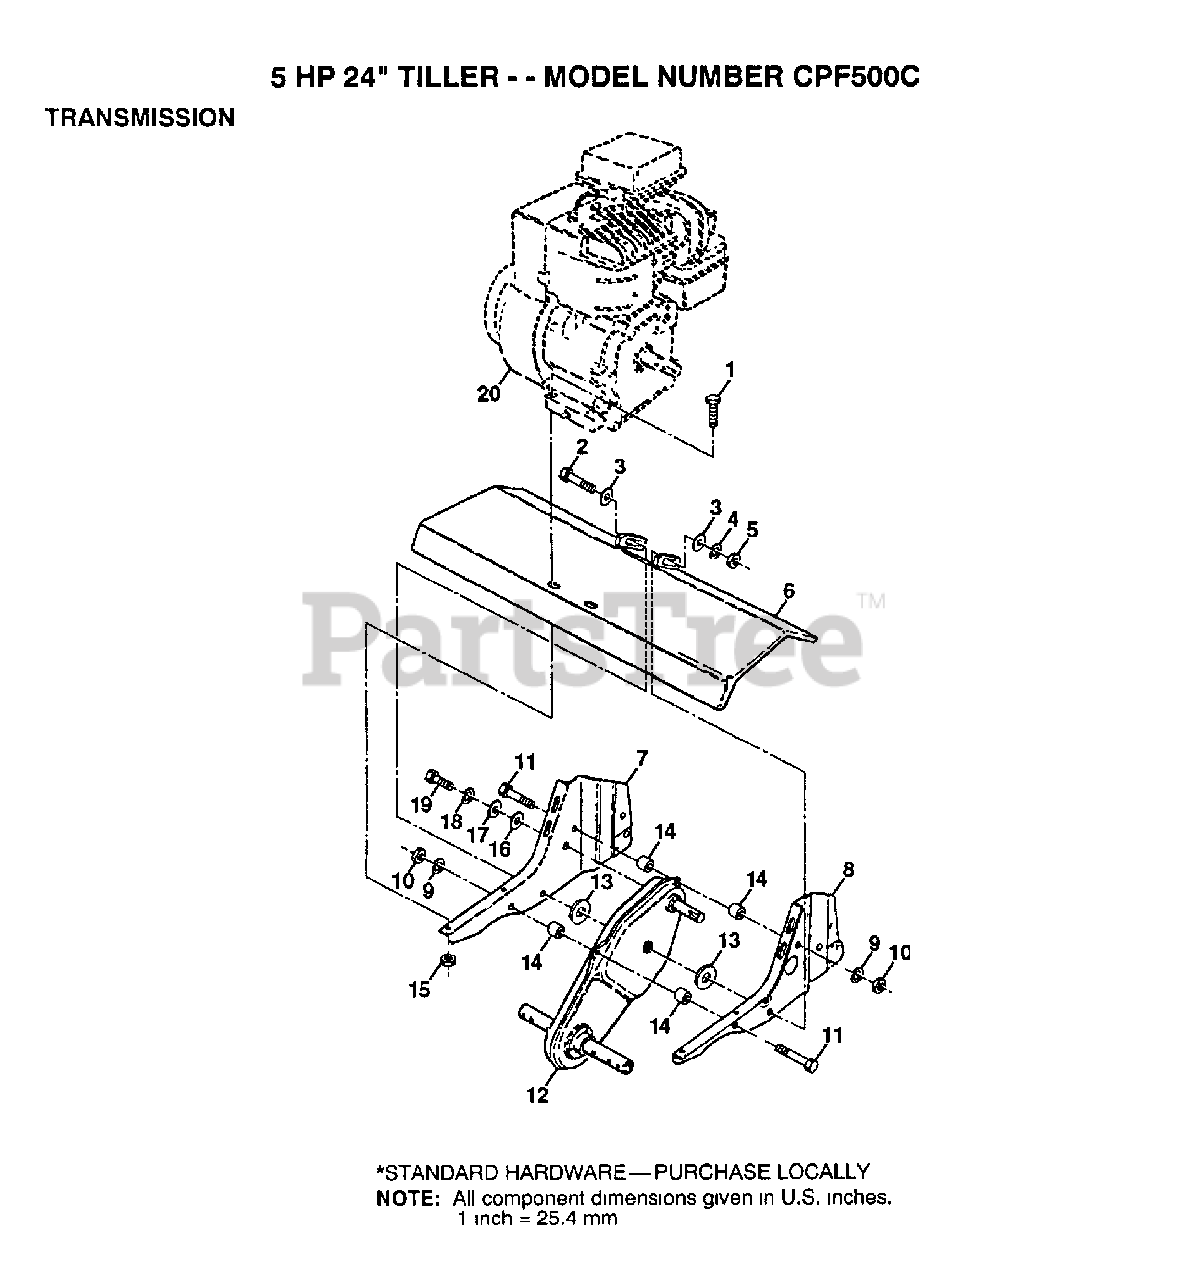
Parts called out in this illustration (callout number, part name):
1	BOLT.HEX.5/16-1.5
2	BOLT.3/8-24X3.75
3	WASHER
4	LOCKWASHER
5	GRIPCO NUT
8	BRACKET.ENG.LH.
9	LOCKWASHER
10	NUT.HEX.5/16-18
14	SPLIT SPACER RT
16	WASHER
17	WASHER
18	LOCKWASHER
19	BOLT
